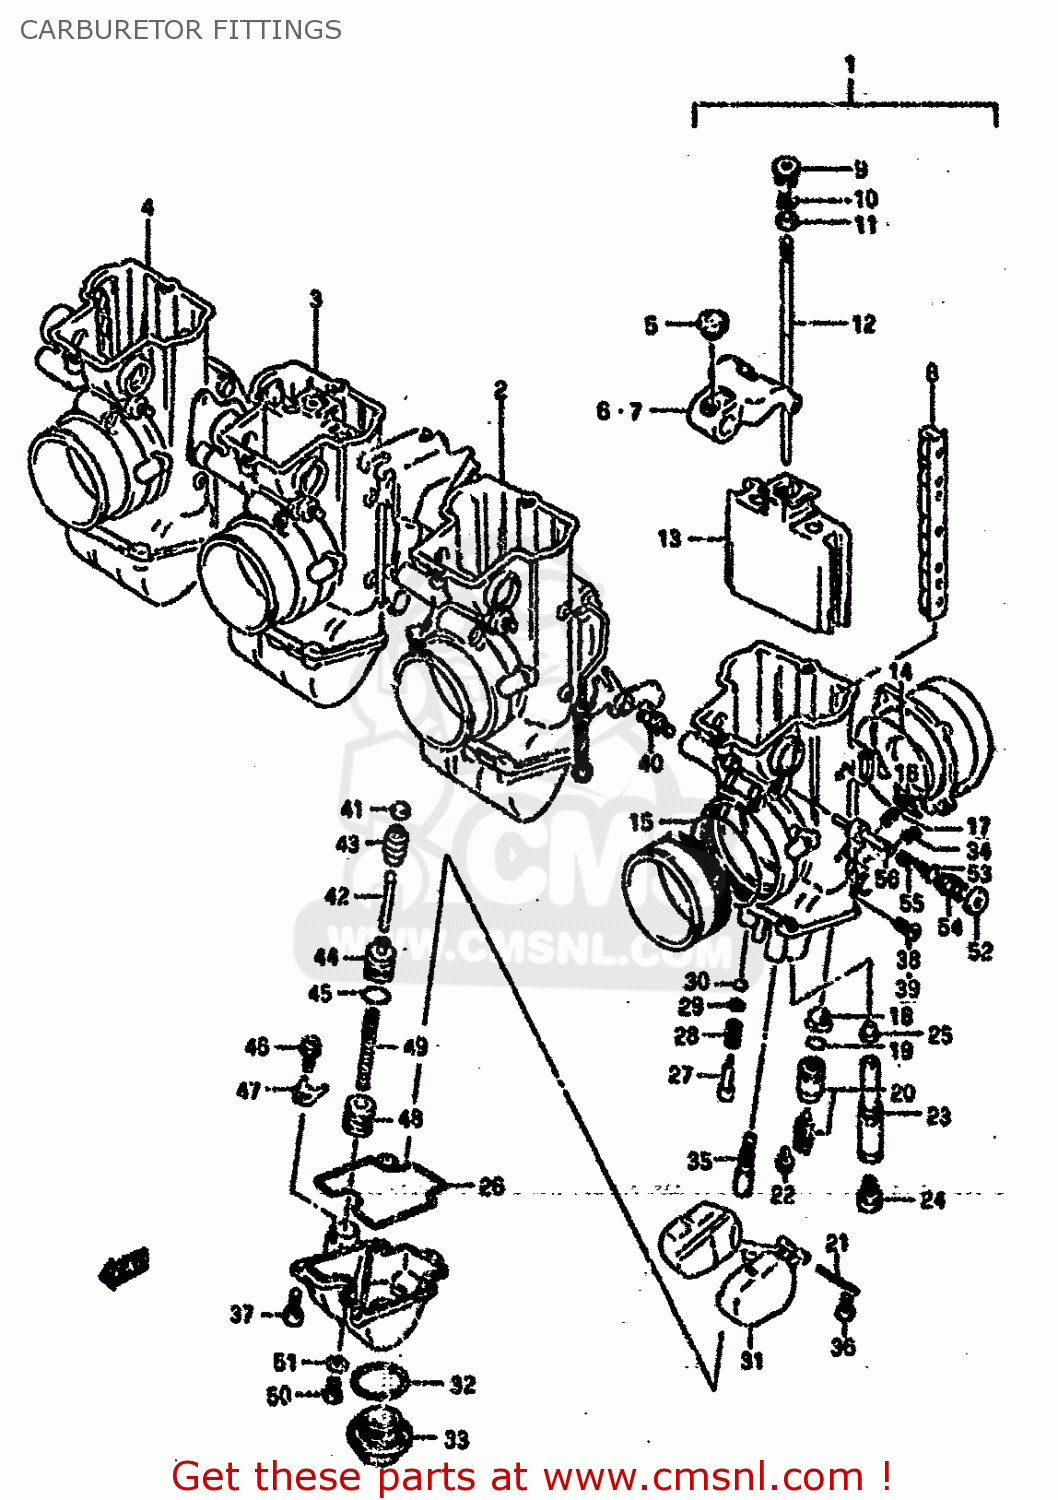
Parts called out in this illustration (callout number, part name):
1	SENSOR
2	SEAL
3	SEAL
4	SEAL,THROTTLE SHAFT
5	E RING
6	GASKET,THROTTLE SHAFT (NAS)
7	BOLT
8	RING
9	RING
10	SCREW
11	SCREW
12	PIN
13	CAP,TOP
14	SCREW
15	WASHER
16	GASKET
17	GASKET,THROTTLE SHAFT (NAS)
18	SCREW
19	BRACKET ASSY
20	LEVER
21	CAP
22	SCREW
23	ADJUSTER ASSY
24	HOSE
25	WASHER
26	SPRING
27	WASHER
28	SCREW
29	HOSE (ID:3.5X0D:6.5XL:200)
30	3-WAY
31	HOE (ID:3.5X0D:6.5XL:40)
32	HOSE (ID:3.5X0D:6.5XL:80)
33	HOSE (ID:3.5X0D:6.5XL:150)
34	CLAMP
35	HOSE (L:40)
36	HOSE (L:45)
37	CLIP
38	SEAL
39	NIPPLE
40	HOSE
41	HOSE
42	CLIP
43	E-RING
44	SCREW
45	NUT
46	BOLT
